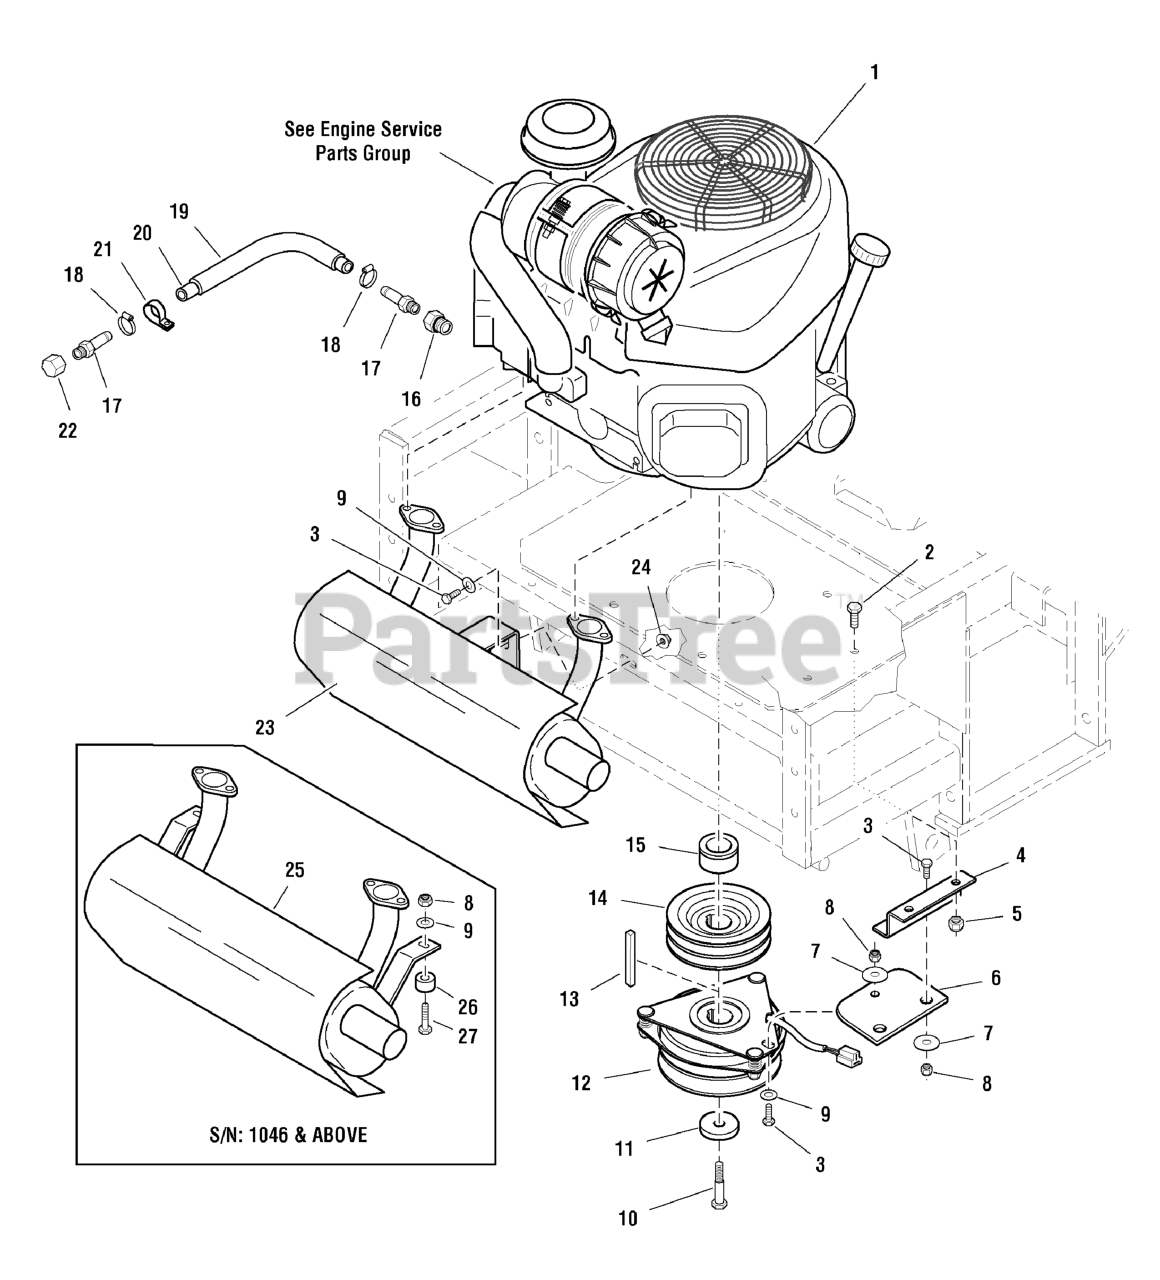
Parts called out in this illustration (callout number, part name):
2	BOLT, 3/8-16 X 1" GD5 CZ
3	BOLT, 5/16-18 X 3/4 GD5
4	ANCHOR, CLUTCH - BLK
5	NUT, 3/8-16 HEX NYLON LOCK
6	CLUTCH ANCHOR PAD
7	WASHER, 3/8" Fender
8	NUT, 5/16-18 Hex Nylon Lock
9	WASHER, 5/16" SAE
10	CRANKSHAFT BOLT, 7/16 x 2-1/4
11	SPACER, .45 x 1.88 x .38
12	ELECTRIC CLUTCH
13	KEY, 1/4 SQ. X 3
14	CRANKSHAFT PULLEY
15	SPACER, 1.13 x 1.75 x 1.03
16	ADAPTER, Oil Drain
17	FITTING, 3/8NPT-1/2" Hose, Straight
18	CLAMP, #6 Hose
19	WIRE LOOM, 12"
20	HOSE, 13"
21	CLAMP, Vinyl
22	CAP, 3/8 NPT
24	NUT, 5/16-18 HEX SERRATED FLANGE (SMALL)
25	MUFFLER, 21HP-25HP KAWASAKI ENGINES
26	SPACER, .39 x 1.00 x .75
27	BOLT, 5/16-18 x 1-1/2
